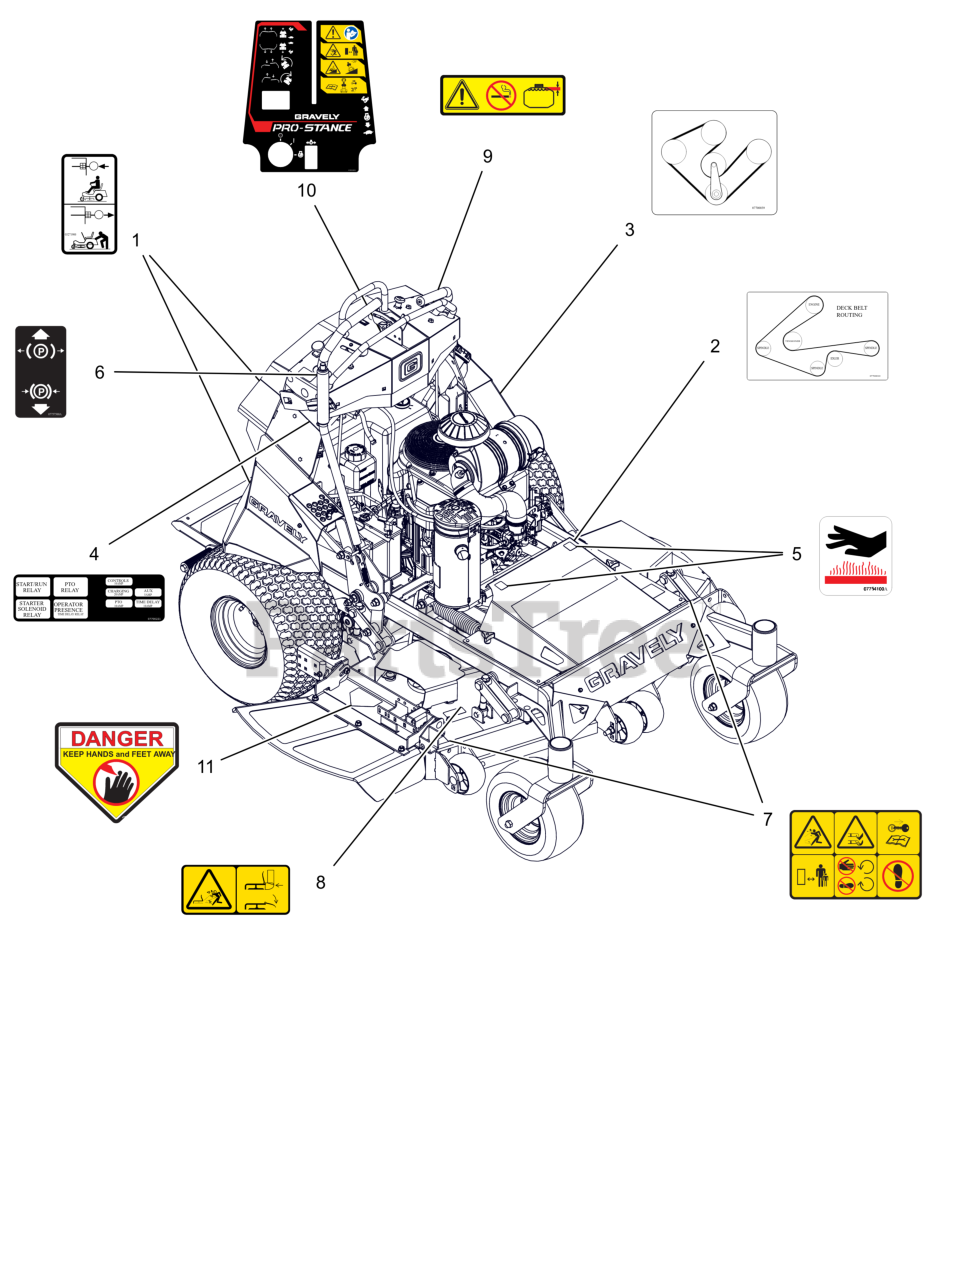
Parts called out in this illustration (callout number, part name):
1	DECAL, TRANSMISSION DISCONNECT
2	DECAL, BELT ROUTING 48/52
3	DECAL, PROSTANCE HYD BELT ROUT
4	DECAL, FUSE BOX
5	DECAL, HOT SURFACE
6	DECAL, PARKING BRAKE LEVER
7	DECAL, SAFETY - MOWER DECK
8	DECAL, SAFETY - DECK GUARDING
9	DECAL, FUEL WARNING
10	DECAL, DASH - PROSTANCE
11	DECAL, DANGER
